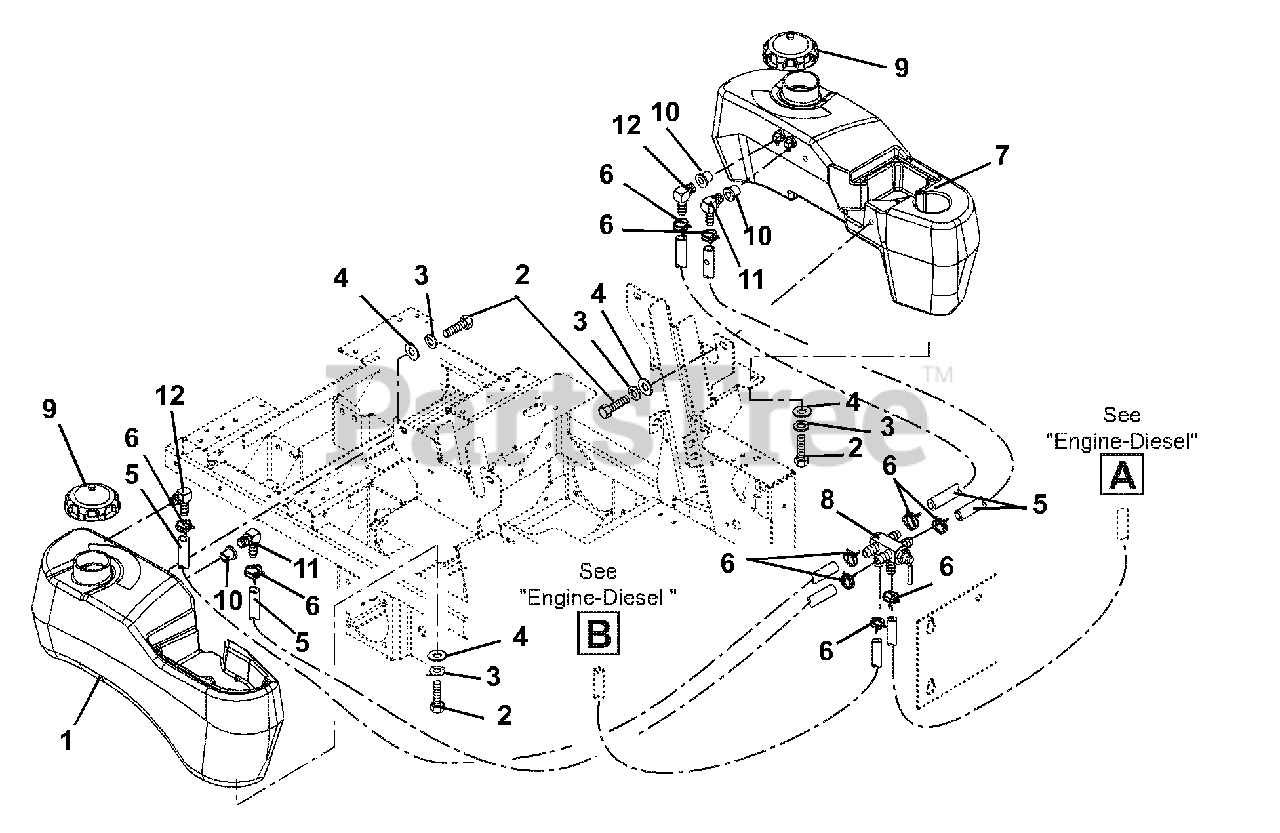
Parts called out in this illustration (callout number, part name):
1	Tank, Fuel-Right Hand (060, 061, 075, 076, 318, 319)
2	Bolt, Hex .31-18 x .75 Grade 5
3	Washer, Locking .31 x .078
4	Washer, Flat Steel .38 x .875 x .083
5	Hose, .31 ID (060, 061, 075, 076, 318, 319)
6	Clamp, Hose Wire .52/.55 (060, 061, 075, 076, 318, 319)
7	Tank, Left Hand Fuel (EYE-Q) 200 Series-EFI (060, 061, 075, 076, 318, 319)
8	Valve, Fuel (060, 061, 075, 076, 318, 319)
9	Cap, Fuel (060, 061, 075, 076, 318, 319)
11	Fitting, Tank (060, 061, 075, 076, 318, 319)
12	Fitting, Tank (060, 061, 075, 076, 318, 319)
